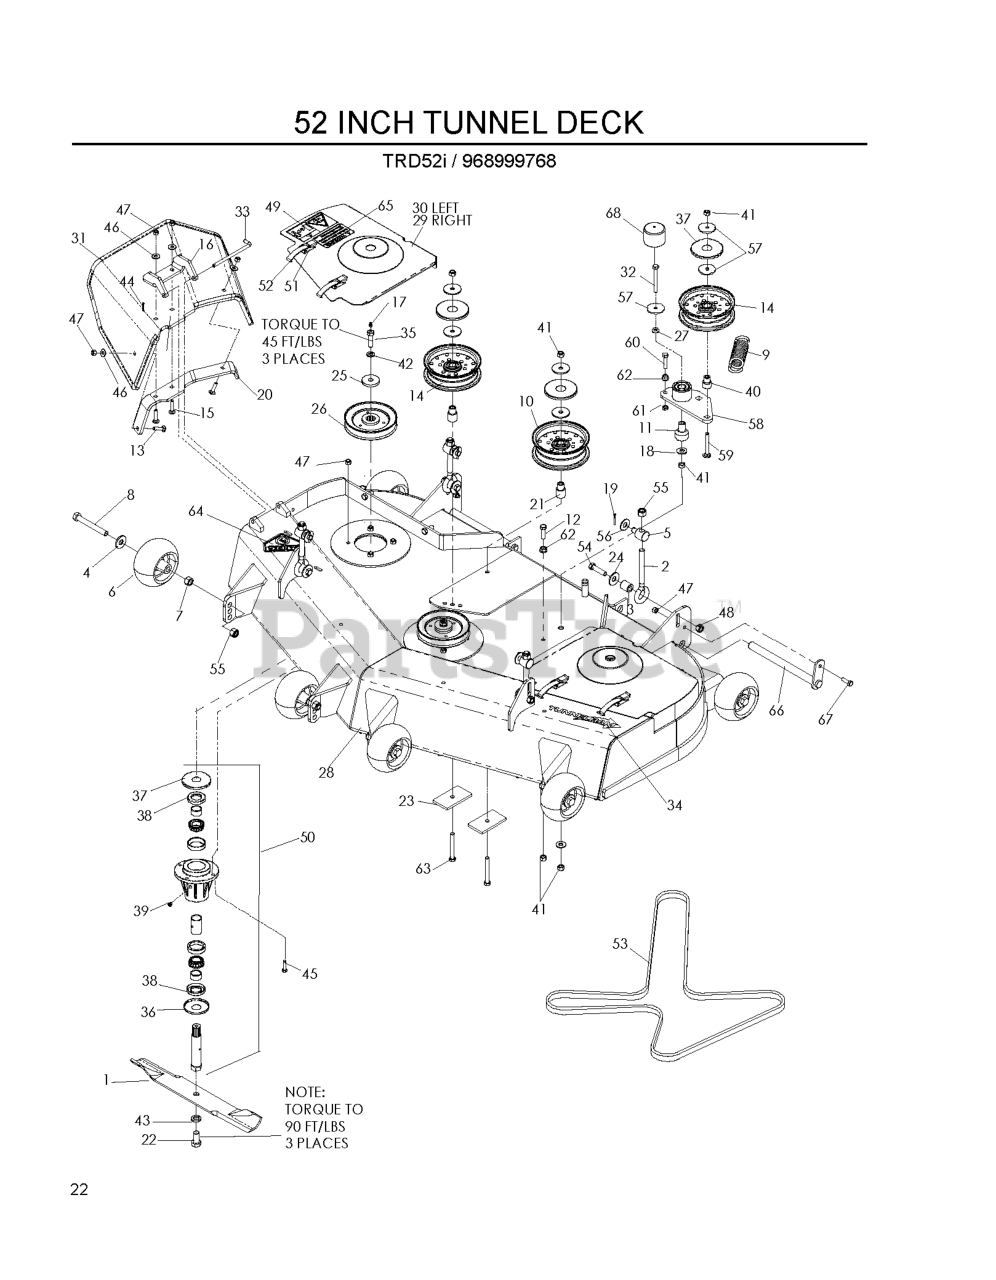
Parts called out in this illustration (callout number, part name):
1	BLADE OEM 18"
4	WASH USS FLAT 1/2
6	GAUGE WHEEL
7	NUT HEX 1/2
8	HHB, 1/2-13X4
9	DECK SPRING
10	IDLER PULLEY (TALL)
11	PIVOT, BEARING
12	HCS 3/8C X 1 1/4 GR5
13	BOLT, CARRIAGE 5/16X1-1/4
14	IDLER PULLEY
15	RHSNB 5/16-18 X 1-1/2 GR 5 ZD
16	PIVOT BRACKET - RUBBER CHUTE
17	ZERK
18	WASHER 3/8 FLAT
19	WASHER 1/2 FLAT
20	BRACKET, REINF-CHUTE
21	IDLER BUSHING
22	HCS 5/8F X 1 1/4
23	SUPPORT PLATE
24	SPRING WASHER - .50
25	SPINDLE WASHER
26	PULLEY, 52
27	WASHER 3/8 SAE FLAT
28	DECK W/DECALS 52" HUS
29	52" BELT SHIELD ASM - RH
30	52" BELT SHIELD ASM - LH
31	CHUTE, RUBBER DISCHARGE 52/61"
32	HCS 3/8C X 3
33	PIN, CHUTE PIVOT
34	DECAL, TUNNEL RAM 8"
35	HCS 7/16-20 GD 8 SPEC
36	BOTTOM DUST CAP
37	TOP DUST CAP
38	SHAFT SEAL
39	PLUG-VENTED
40	BUSHING, IDLER
41	NUT 3/8-16 NYLOC
42	WASHER 7/16 LOCK
43	LOCKWASHER 5/8
44	RP_COTTER PIN 1/8 X 3/4
45	HCS 5/16C X 1 1/4
46	WASHER 5/16 FLAT
47	NUT 5/16 NYLOC
48	NUT 7/16C CENTERLOCK
49	DECAL, EURO SEVERING
50	HOUSING ASM, 52/61
51	RIVET, BLIND, 5/32 DIA
52	DRAW LATCH
53	BELT, DECK
54	HCS 7/16 - 14 X 1 3/4
55	NUT 1/2-13 HEX NYLOC ZD
56	PIN COTTER 1/8 X 1 ZD
57	WASHER, 3/8 SPEC
58	ARM-IDLER W/BRG
59	RHSNB 3/8-16 X 2.75
60	HCS 3/8-16 X 1-1/2
61	NUT 3/8-16 HEX JAM
62	NUT 3/8C WHIZ
63	HCS 3/8C X 3
64	DECAL, CPSC
65	DECAL, CAUTION
67	HCS 5/16C X 1
68	CAP, VINYL
